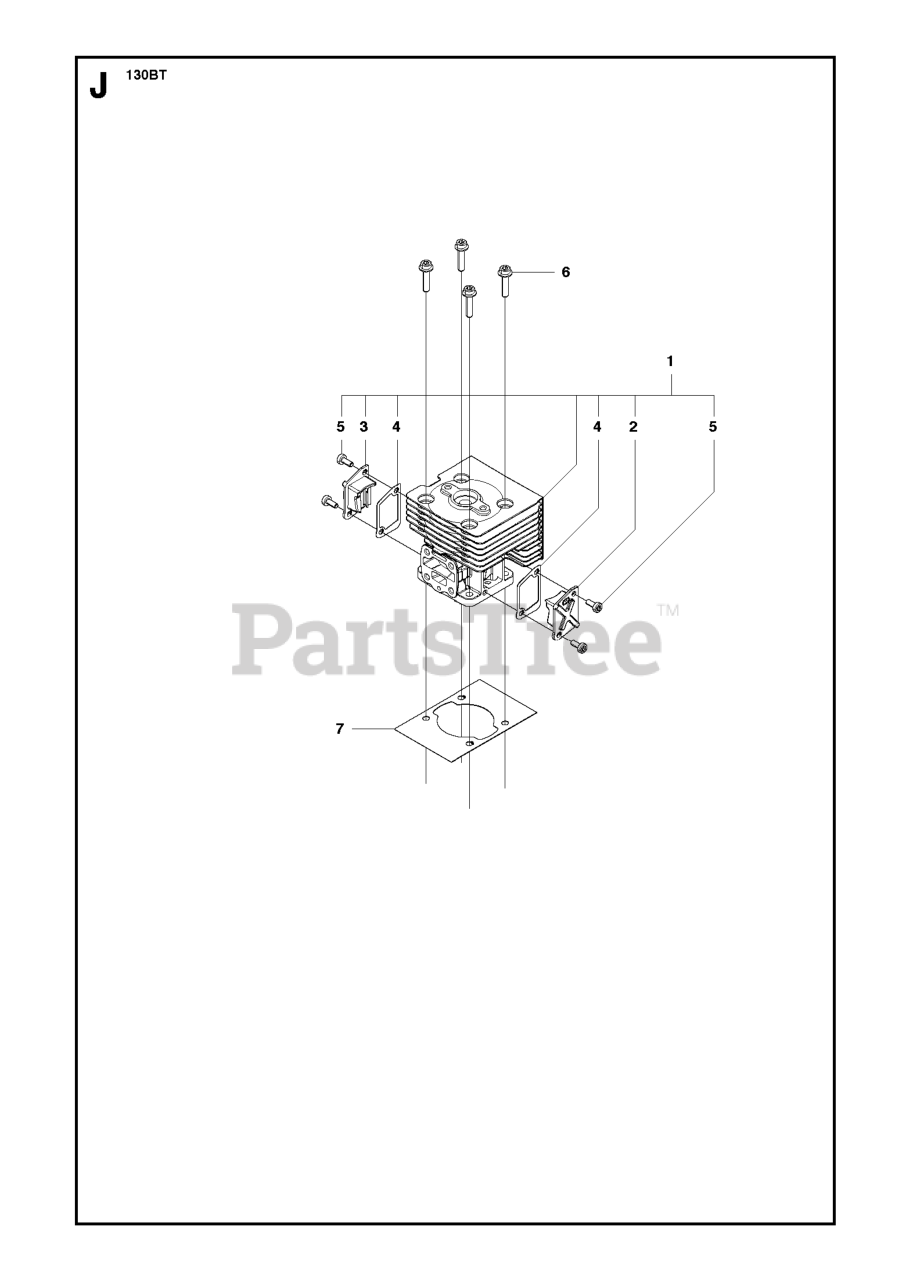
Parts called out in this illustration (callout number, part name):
1	CYLINDER
2	COVER TR(S)
3	COVER TR (F)
7	GASKET BASE
